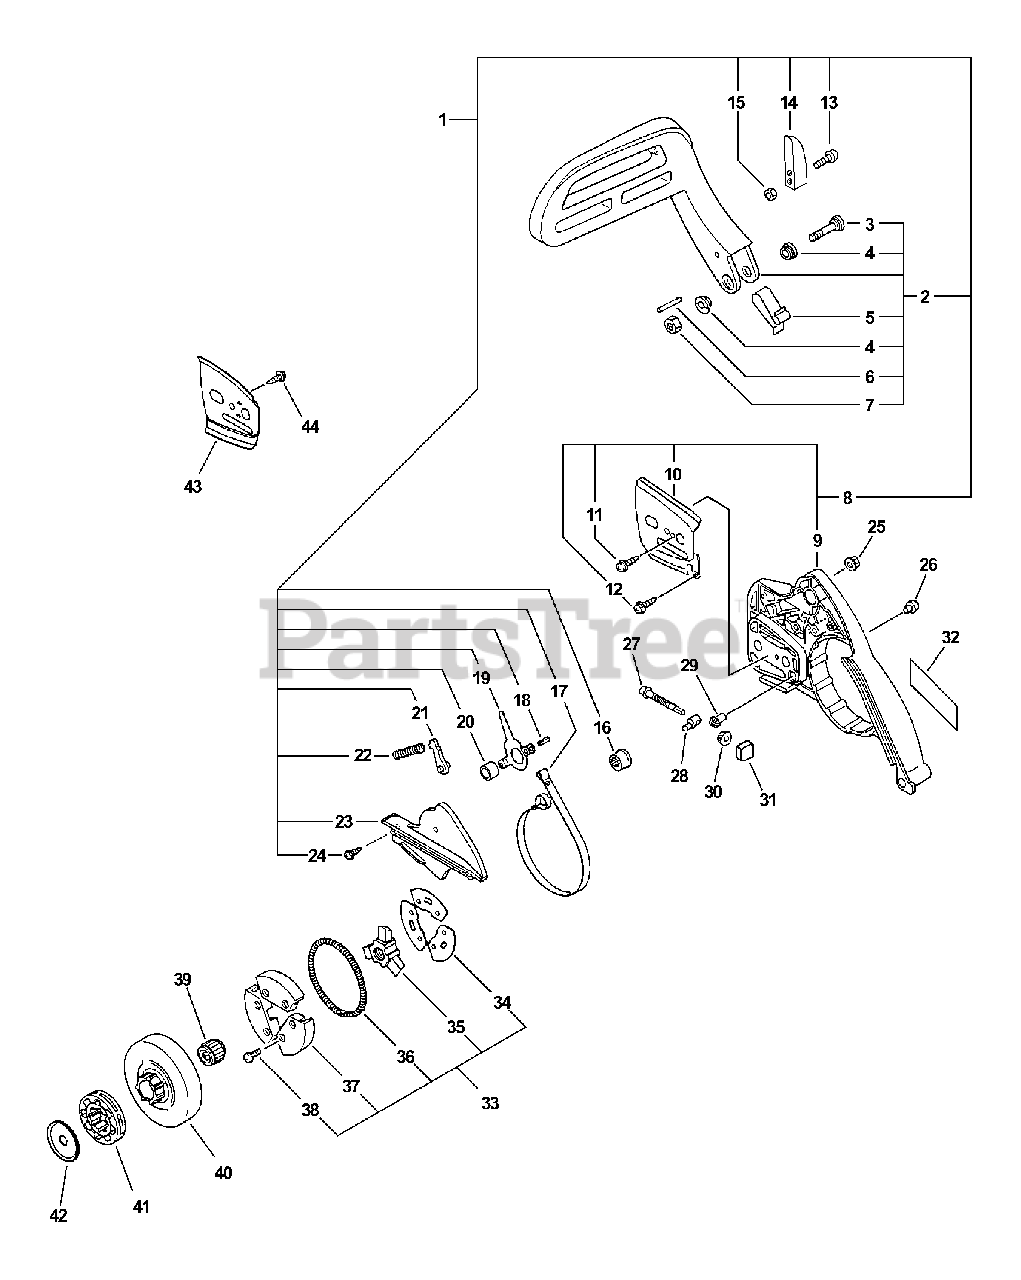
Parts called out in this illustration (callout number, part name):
1	CHAIN BRAKE ASSY
2	BRAKE LEVER ASSY
3	SCREW 5×32
4	COLLAR 5.3×10×13×L5
5	SPRING, FLAT
6	PIN 3×26
7	NUT, LOCK M5
8	SPROCKET GUARD ASSY
9	GUARD, SPROCKET
10	PLATE, GUIDE - OUTER
11	SCREW 3×6
12	SCREW 4×10
13	SCREW 4×18
14	WEIGHT, BRAKE
16	ADJUSTER, BRAKE
17	BAND, BRAKE
18	PIN, SPRING 4×8.8
19	LEVER, BRAKE
20	WASHER 5.2×12×14
21	STOPPER, BRAKE
22	SPRING, COMPRESSION
23	COVER, BRAKE
24	SCREW 4×10
25	NUT, FLANGE M8×1.25
28	TENSIONER, CHAIN
29	GEAR, BEVEL
30	GEAR, BEVEL
31	COLLAR - 8
32	LABEL - ECHO
33	CLUTCH ASSY
34	PLATE, CLUTCH
35	HUB, CLUTCH
36	SPRING, CLUTCH
37	SHOE SET, CLUTCH (3PCS)
38	BOLT 4×6
39	BEARING, NEEDLE
40	DRUM, CLUTCH
41	SPROCKET, 0.325 RIM
42	PLATE, CLUTCH
43	PLATE, GUIDE - INNER
44	SCREW 4×6
